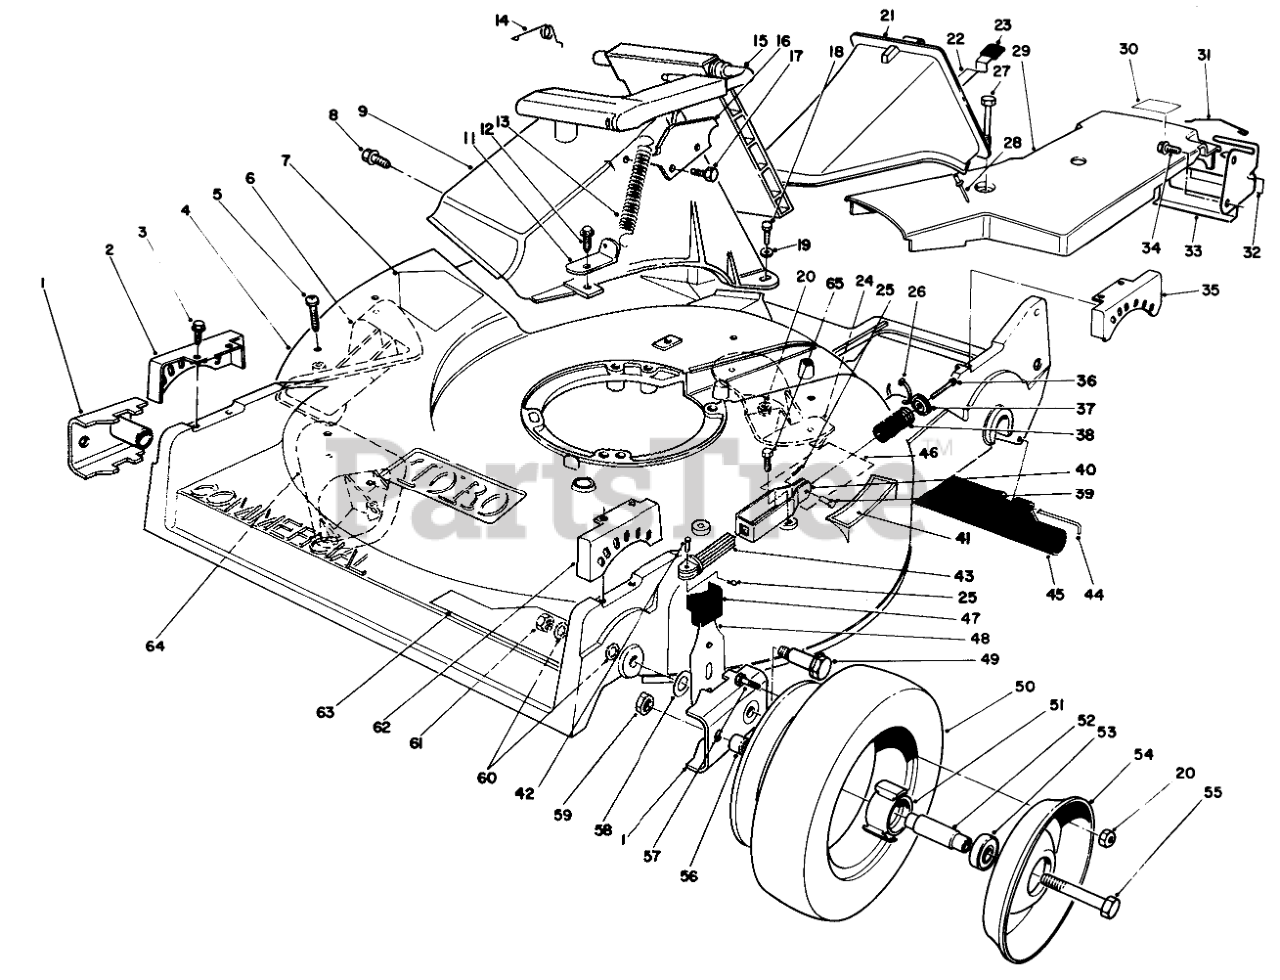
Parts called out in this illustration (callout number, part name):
1	ARM-PIVOT, FRONT
2	QUADRANT-FRONT, RH
3	SCREW-HWHTF
4	Housing-Commercial (Incl. Ref. #5-7, 24, & 64)
5	SCREW-PPH
6	KICKER-RH
7	DECAL-DANGER
8	SCREW AND WASHER ASM
9	DISCHARGE TUNNEL
11	BRACKET-SPRING
12	SCREW-HWH
13	SPRING-DOOR
14	RETAINER-DOOR
15	DOOR ASSEMBLY
16	DOOR LATCH PLATE
17	SCREW-PLASTITE
18	SCREW-HH
19	WASHER-FLAT
20	NUT-LOCK, NI
21	Plug-Discharge (Incl. Ref. #22, 23, & 28)
22	LATCH-PLUG, DISCHARGE
23	GRIP-LATCH
24	KICKER-REAR
25	PIN-COTTER
26	TIE-CABLE
27	SCREW-HHFTF
28	RIVET-HEAD, FLAT
29	Cover-Belt
30	LABEL-GREASE
31	RETAINER-CABLE
32	DECAL-POSITION, GEAR
33	BRACKET-ADJUSTMENT, TRACTION
34	SCREW-HWHTF
35	QUADRANT-REAR, LH
36	SCREW-HWHTF
37	RETAINER-SPRING
38	SPRING
39	PIN-CABLE
40	Bracket-Spring
41	STEP PAD DECAL
42	PIN-SPRING
43	GUIDE-SPRING
44	ROD-SHIELD
45	SHIELD-TRAILING
46	DECAL - DANGER, COVERS
47	KNOB-ARM
48	FRONT SPRING ARM ASM
49	BOLT-WHEEL
51	HUB-BEARING
52	SPACER-BEARING
53	BEARING-WHEEL
54	Wheel-Half
55	SCREW-HH
56	SPACER-WHEEL
57	SCREW-HH
58	WASHER-THRUST
59	NUT-LOCK, CONE
60	WASHER
61	NUT-LOCK
62	QUADRANT-FRONT, LH
63	DECAL - RECYCLER
64	KICKER-FRONT
65	SCREW-HH
